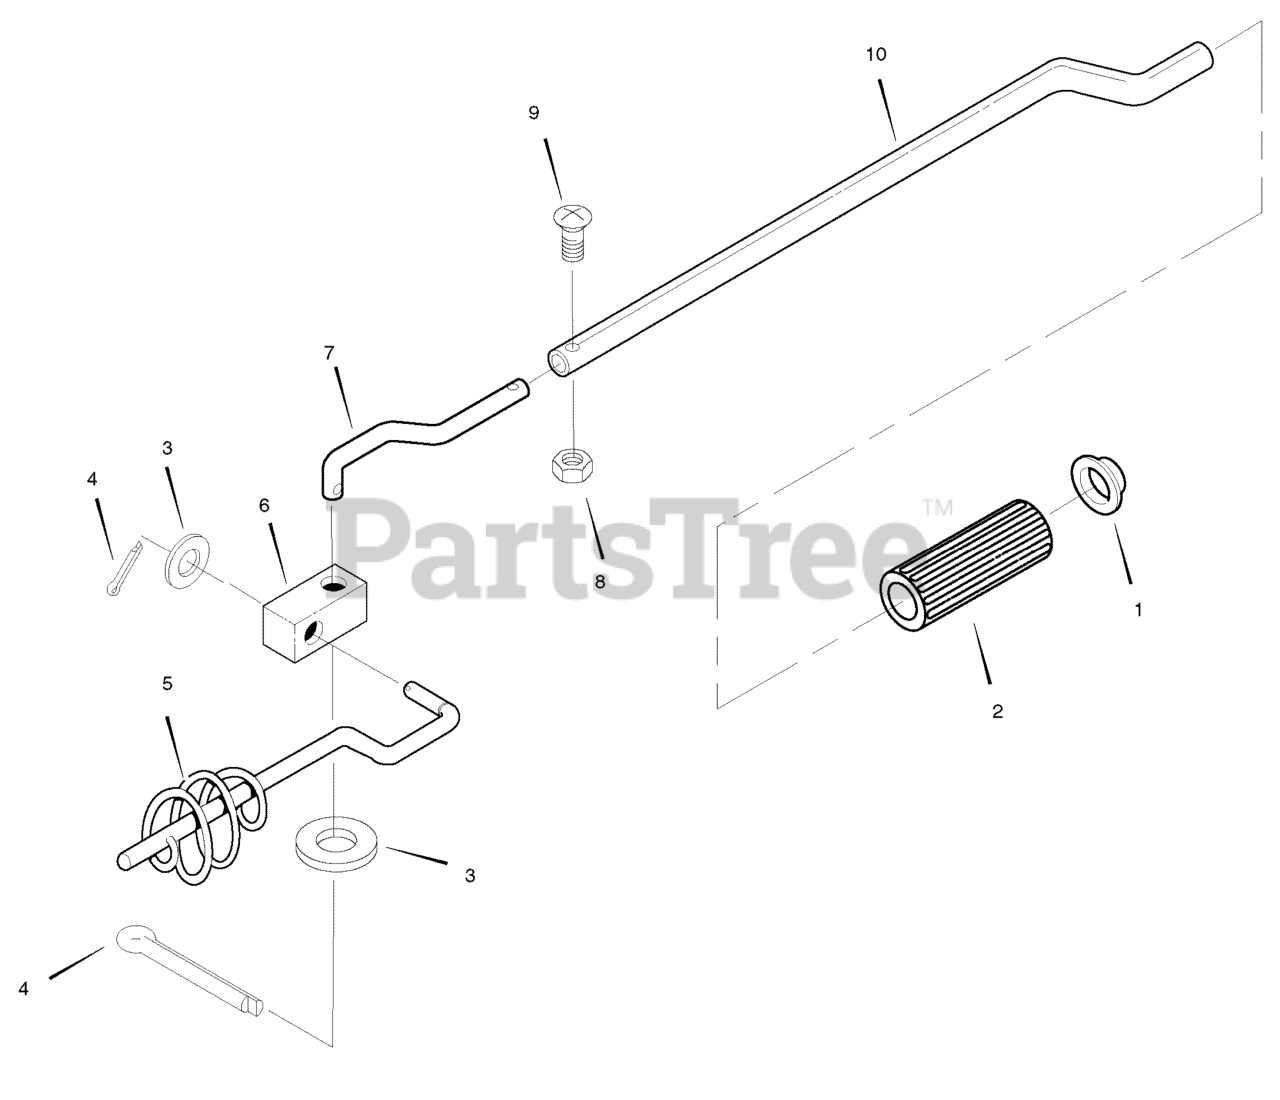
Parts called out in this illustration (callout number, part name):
1	PUSH NUT
2	KNOB, GRIP
3	WASHER, FLAT .400x.75x.02
4	PIN, COTTER
5	ROD, CHUTE CNTRL LWR
6	BLOCK, PIVOT
7	ROD, CHUTE CNTRL MID
8	NUT, LOCK 10-32
9	SCREW, 10-32X.88
10	ROD, CHUTE UPPER
